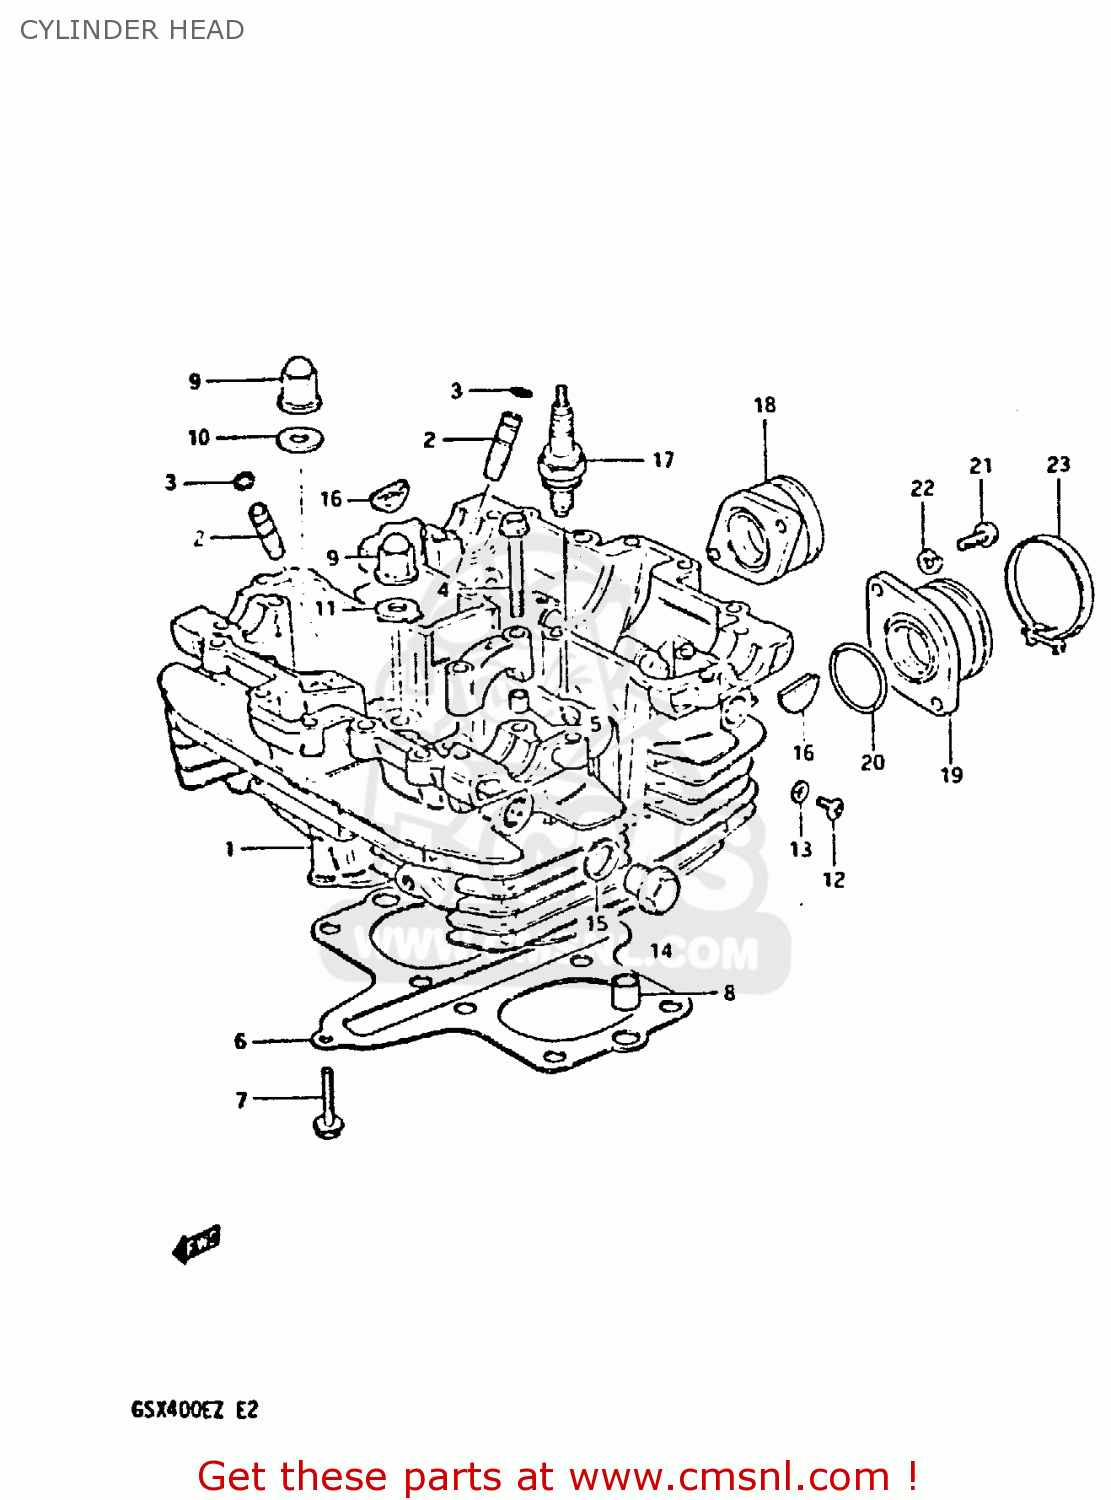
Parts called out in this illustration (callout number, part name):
1	CYLINDER HEAD SET
2	GUIDE,INTAKE VALVE
3	RING,SNAP
4	BOLT(6X39)
5	PIN(6.2X8X11)
6	GASKET (MCA)
7	BOLT
8	PIN
9	NUT
10	GASKET(10.5X22X2) (NAS)
11	GASKET(10X22X2.3) (NAS)
12	SCREW
13	GASKET(5.3X9.3X1.2) (NAS)
14	PLUG (14X12)
15	GASKET(14X19.2X2) (NAS)
16	PLUG
17	SPARK PLUG DR8ES-L
18	PIPE,INTAKE,R
19	PIPE,INTAKE,L
20	O-RING
21	SCREW
22	LOCK WASHER
23	CLAMP
